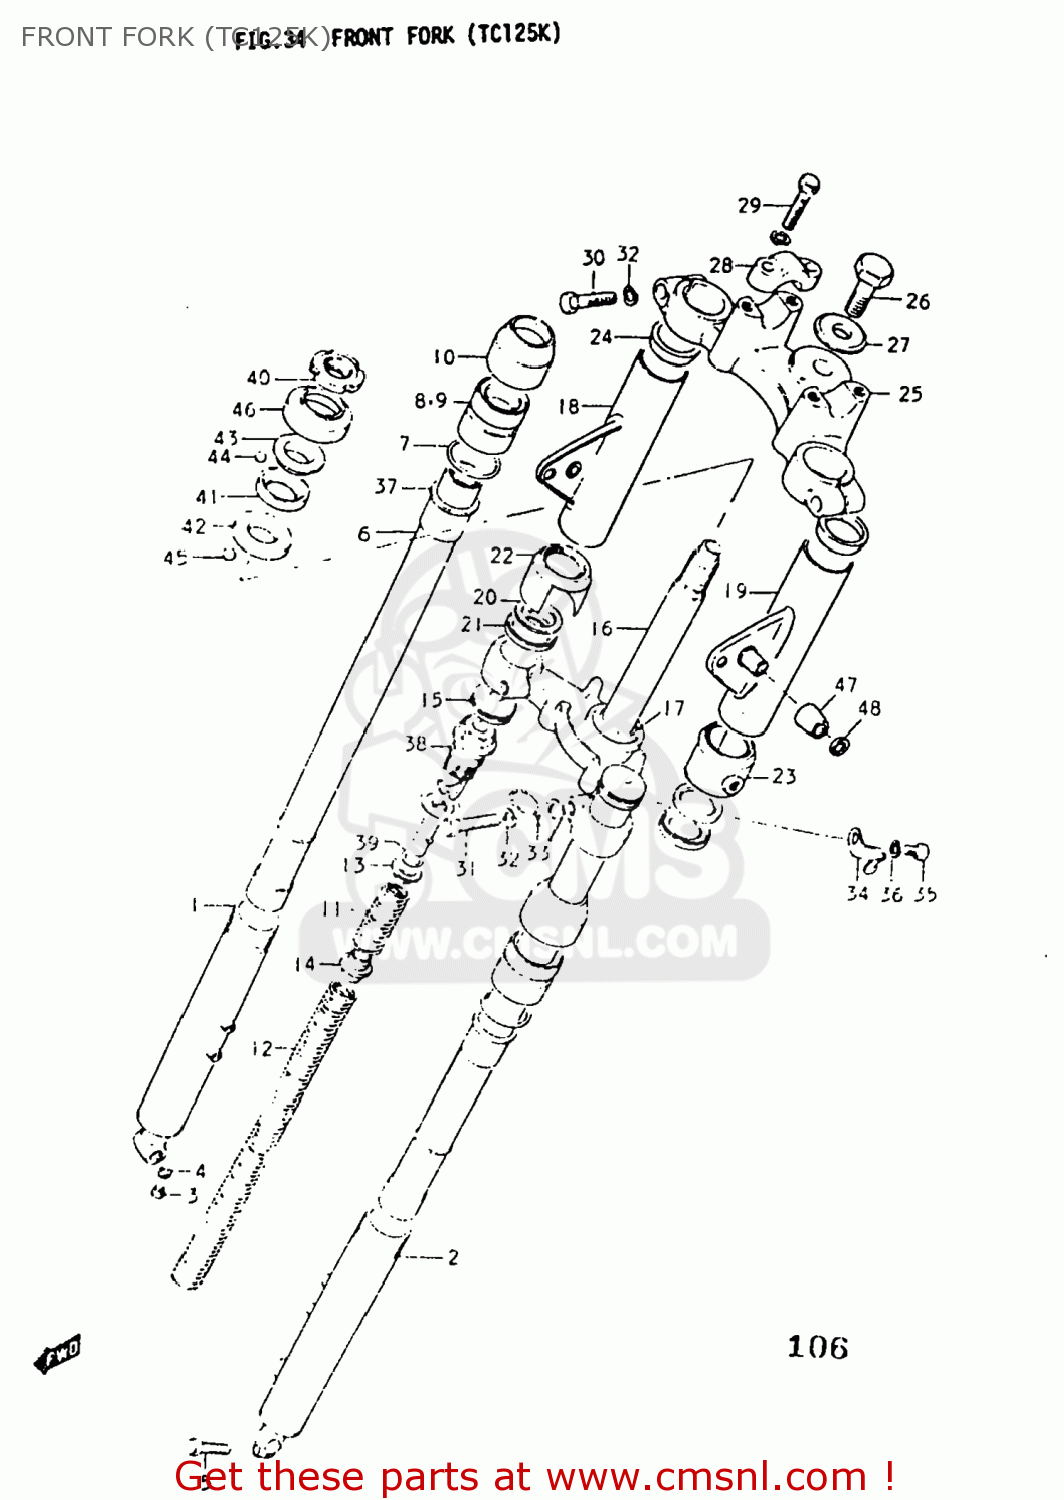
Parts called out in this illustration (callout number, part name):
1	TUBE,OUTER,RIGHT
2	TUBE,OUTER,LEFT
3	SCREW
4	GASKET,DRAIN,PLUG (NAS)
5	BOLT
6	TUBE,FORK,INNER
7	O RING,OIL SEAL LWR
8	NUT,FORK OUTER TUBE
9	SEAL,OIL
10	SEAL,DUST
11	SPRING
12	SPRING,FRONT FORK
13	GUIDE,SPRING
14	JOINT,SPRING
15	CAP,FRONT FORK
16	STEM,STEERING
17	RACE,STEERING OUTER LWR
18	BRACKET,HEADLAMP HOUSING
19	BRACKET,HEADLAMP,LEFT
20	CUSHION,HEADLAMP BRACKET
21	GUIDE, COVER
22	CUSHION,HEADLAMP BRACKET
24	SEAT,HEADLAMP BRACKET
25	HEAD,STEERING STEM
26	BOLT,FORK INNER TUBE
27	WASHER
28	HOLDER,HANDLEBAR
29	BOLT
30	BOLT,FORK INNER TUBE F
31	BOLT,FR FORK LWR(12X33)
32	LOCK WASHER
33	CLIP
34	CLIP
35	SCREW
36	LOCK WASHER
37	BUSHING,GUIDE
38	CAP
39	SEAT,SPRING
40	NUT,STEERING STEM(25X44X10)
41	RACE,STEERING,INNER,UPPER
42	LACE,STEERING INNER LWR
43	RACE,STEERING OUTER UPR
44	BALL
45	BALL
46	DUST SEAL,STEERING UPR
47	COVER,FRONT TURN SIGNAL BRACKET
48	WASHER
